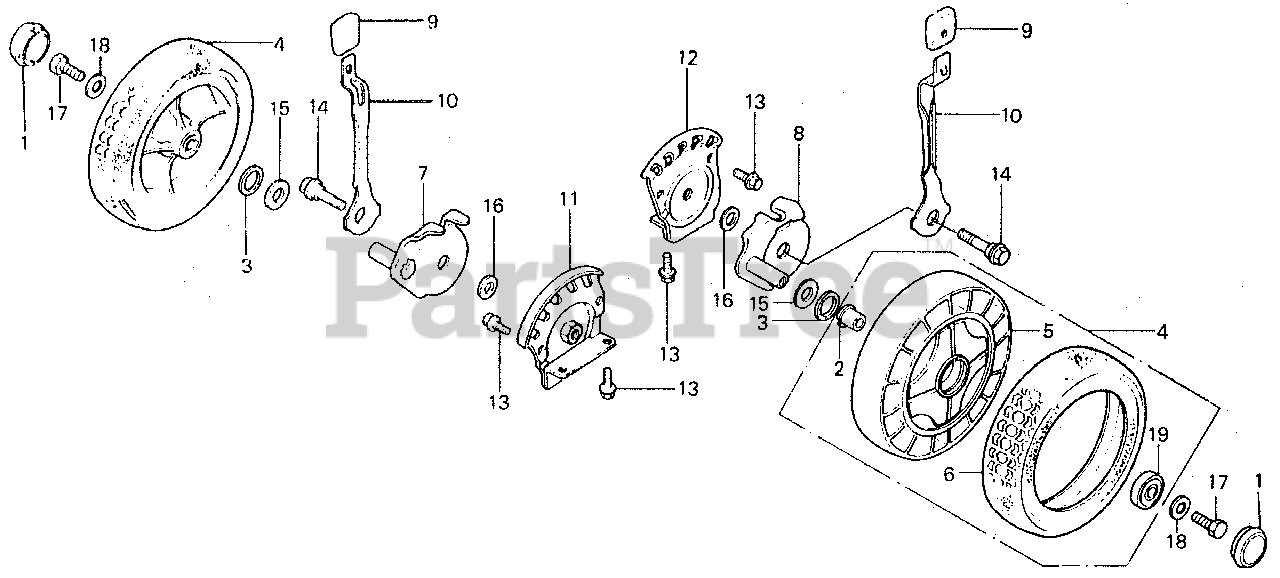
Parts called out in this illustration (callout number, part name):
1	CAP, WHEEL
2	BUSH, WHEEL (NOT AVAILABLE)
3	FELT, WHEEL SHAFT (NOT AVAILABLE)
4	WHEEL ASSY., RR. *NH31* (MCKINLEY WHITE) (NOT AVAILABLE)
5	HUB, RR. WHEEL *NH31* (MCKINLEY WHITE)
6	TIRE, RR. (8INCH)
7	ARM, R. RR. ADJUSTING
8	ARM, L. RR. ADJUSTING
9	GRIP, ADJUSTER
10	PLATE, RR. ADJUSTING (NOT AVAILABLE)
11	PANEL, R. RR. ADJUSTING (NOT AVAILABLE)
12	PANEL, L. RR. ADJUSTING (NOT AVAILABLE)
13	BOLT, FLANGE (6X12) (CT200)
14	BOLT, RR. ADJUSTING ARM
15	WASHER (15MM)
16	WASHER (10MM) (NOT AVAILABLE)
17	BOLT, HEX. (8X12)
18	WASHER, PLAIN (8MM)
19	BEARING, RADIAL BALL (6202UU)
